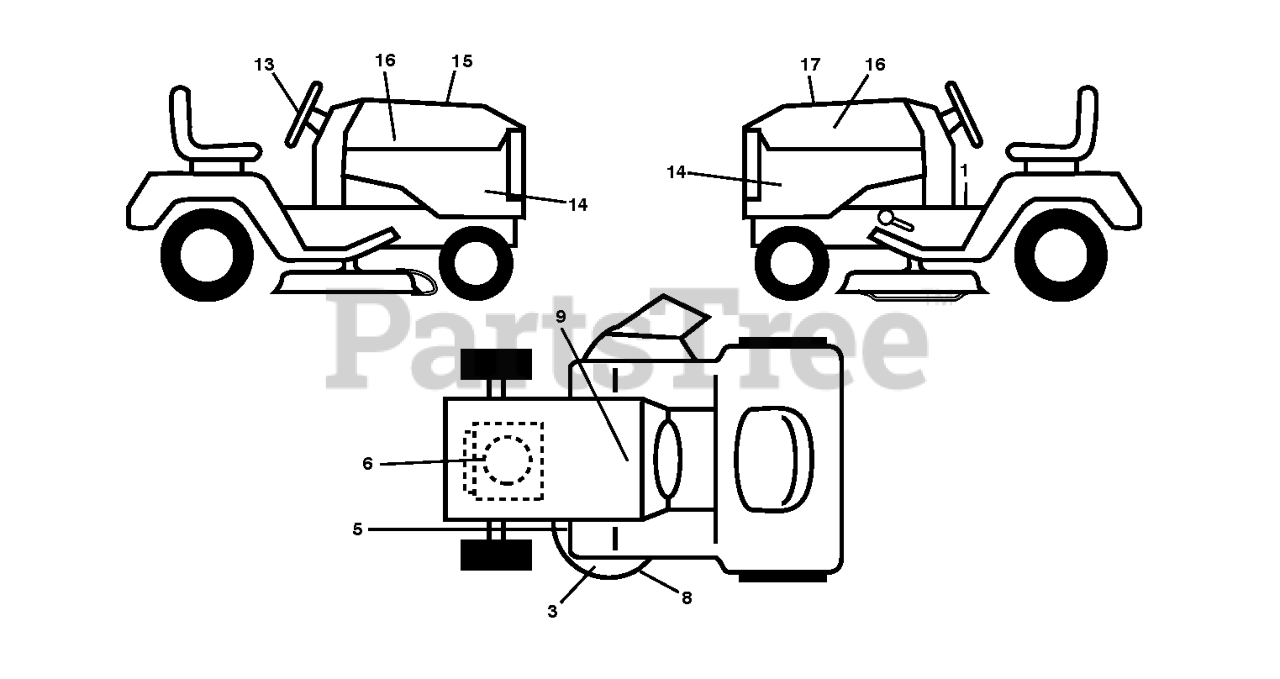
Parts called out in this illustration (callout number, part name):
1	DECAL.FENDER.WARNING.ENG
3	DECAL.WARN.KEEP.HAND.AWAY
5	DECAL CLUTCH/BRAKE
6	DECAL, ENG. HP
8	DECAL.MOWER.SCH.48/54
9	DECAL BTRY SYMBOLS
13	DECAL.WHEEL.STRG.LGN.H
14	DECAL PANEL SIDE
15	DECAL HOOD CUST. RESP.
16	DECAL.HOOD.LOGO.HUSQVARNA
17	DECAL REPLACEMENT
